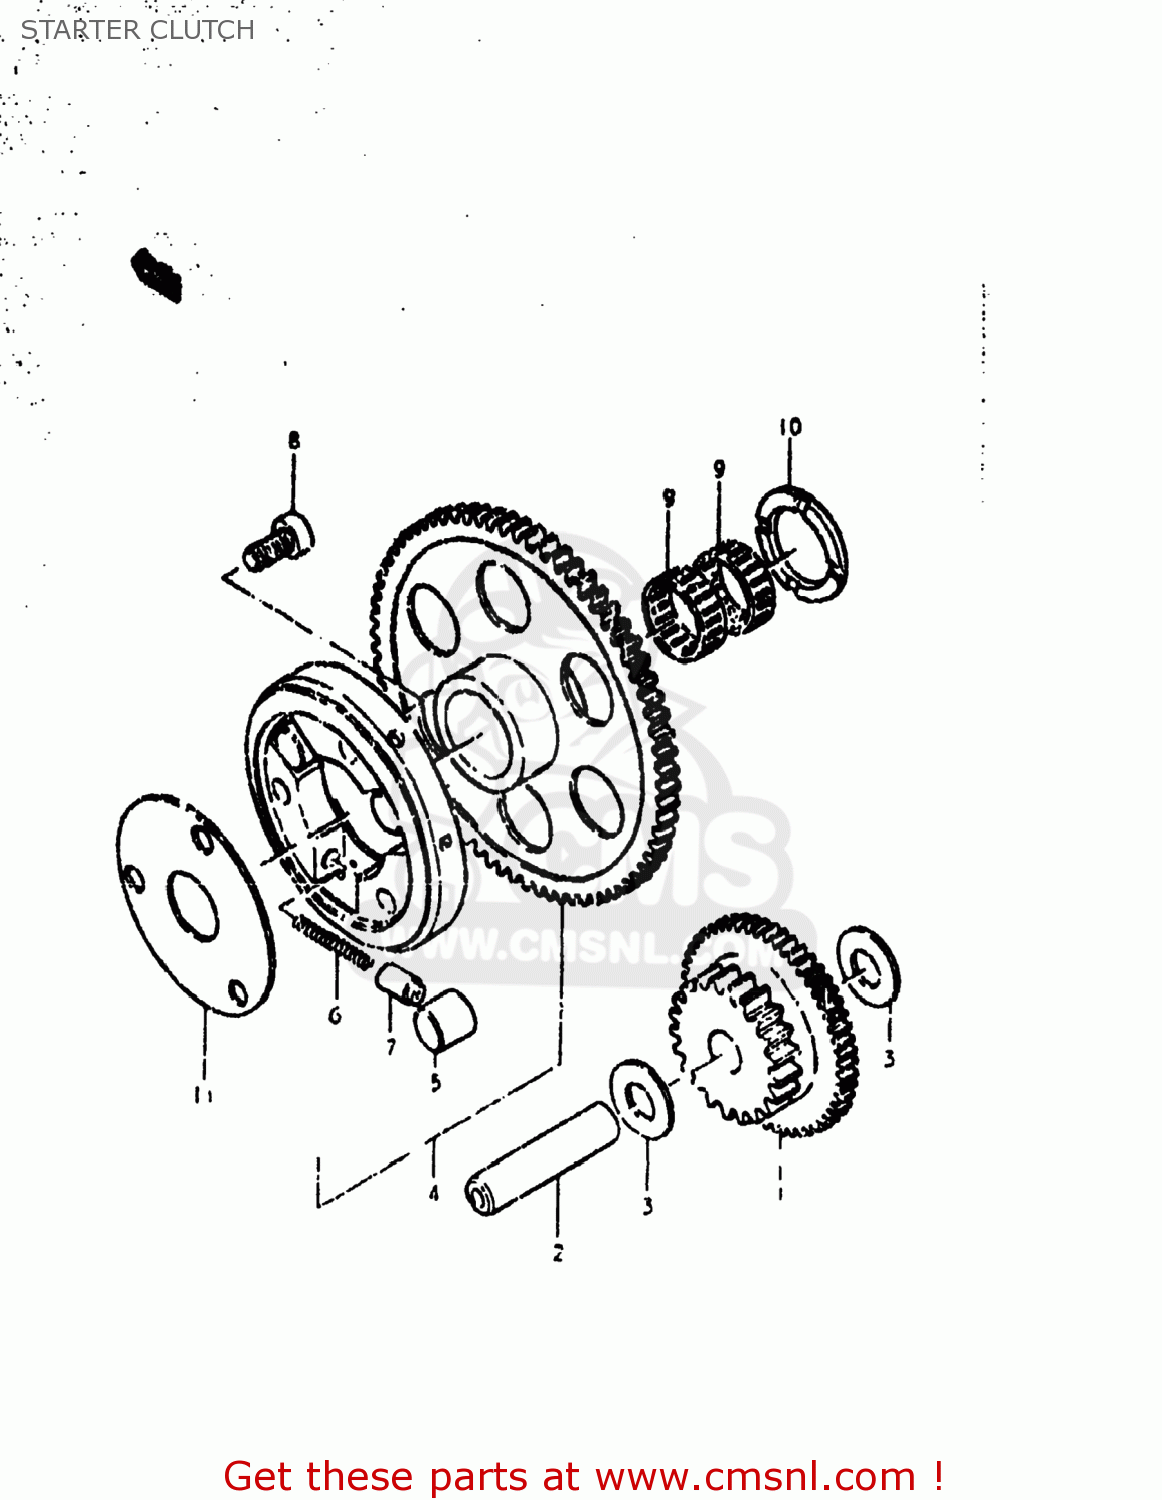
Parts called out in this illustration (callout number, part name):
1	GEAR,STARTER IDLE
2	PIN(7.4X13X56)
3	WASHER(13.3X25X0.85)
4	CLUTCH SET,STARTER
5	ROLLER(15X13)
6	SPRING
7	PIECE,PUSH
8	BOLT
9	BEARING(25X29X9.9)
10	WASHER(25X38X2.5)
11	SHIM,STARTER CLUTCH HUB
